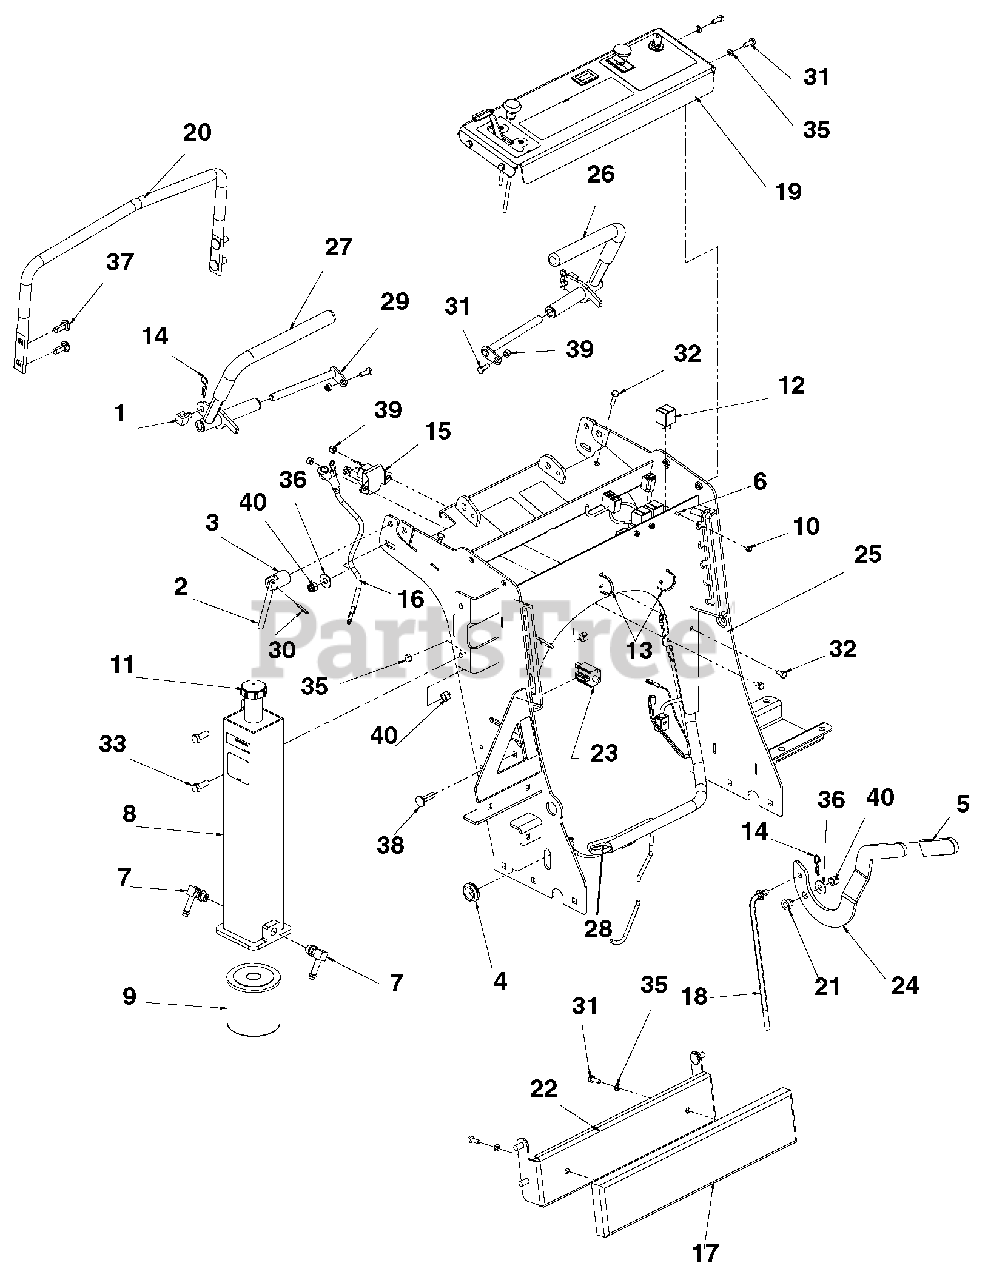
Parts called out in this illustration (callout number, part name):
1	Swivel Adjuster
2	Lever, Lock Y
3	Base, Lock Lever Y
4	Grommet, Rubber .88ID x 1.38OD x .14
5	Grip, PVC .250 x 1.00 x 3.63
6	Screw, 8-32 x .50 Y
7	Fitting, 90 9/16 MOR x 3/8 HOSE
8	Weldment, Reservior Hydraulic
9	Filter, Oil
10	Nut, 8-32 Elastic Stop
11	Cap, Filler Oil
12	Relay, Iso Mini Elec.
13	Cable Tie, .15 x 8.50
14	Pin, Hair .091 x 1.63
15	Solenoid, 12 V Starter
16	Cable, 12" Starter
17	Pad, Thigh
18	Link, Brake
19	Assembly, Control Panel w/Decals (switches sold seperately)
20	Handle, Support
21	Bushing, Brake Pivot Y
22	Weldment, Thigh Pad Bracket
23	Switch, NO-NO-NC Grey Plunger
24	Brake Lever, Offset
25	Weldment, Console 34 w/Decals
26	RH Control Lever w/Grip
27	LH Control Lever w/Grip
28	Harness, Wiring
29	Weldment, Pin and Lock
30	Pin, Spring 5/32 x 1
31	Bolt, Hex .25-20 x .75 Grade 5
32	Bolt, .25-20 x 1.00 Hex 5 Y
33	Bolt, Hex .38-16 x 1.00 Grade 5
34	Nut, .25-20 Standard Hex Grade 5 Y
35	Washer, .250 Med Spring Lock
36	Washer, .375 Reg Flat
37	Bolt, Round Head Square Neck .38-16 x 1.00 G 5
38	Bolt, Round Head Square Neck .38-16 x 1.25 G 5
39	Nut, Locking-Nylon .250-20
40	Nut, Locking-Nylon .38-16
